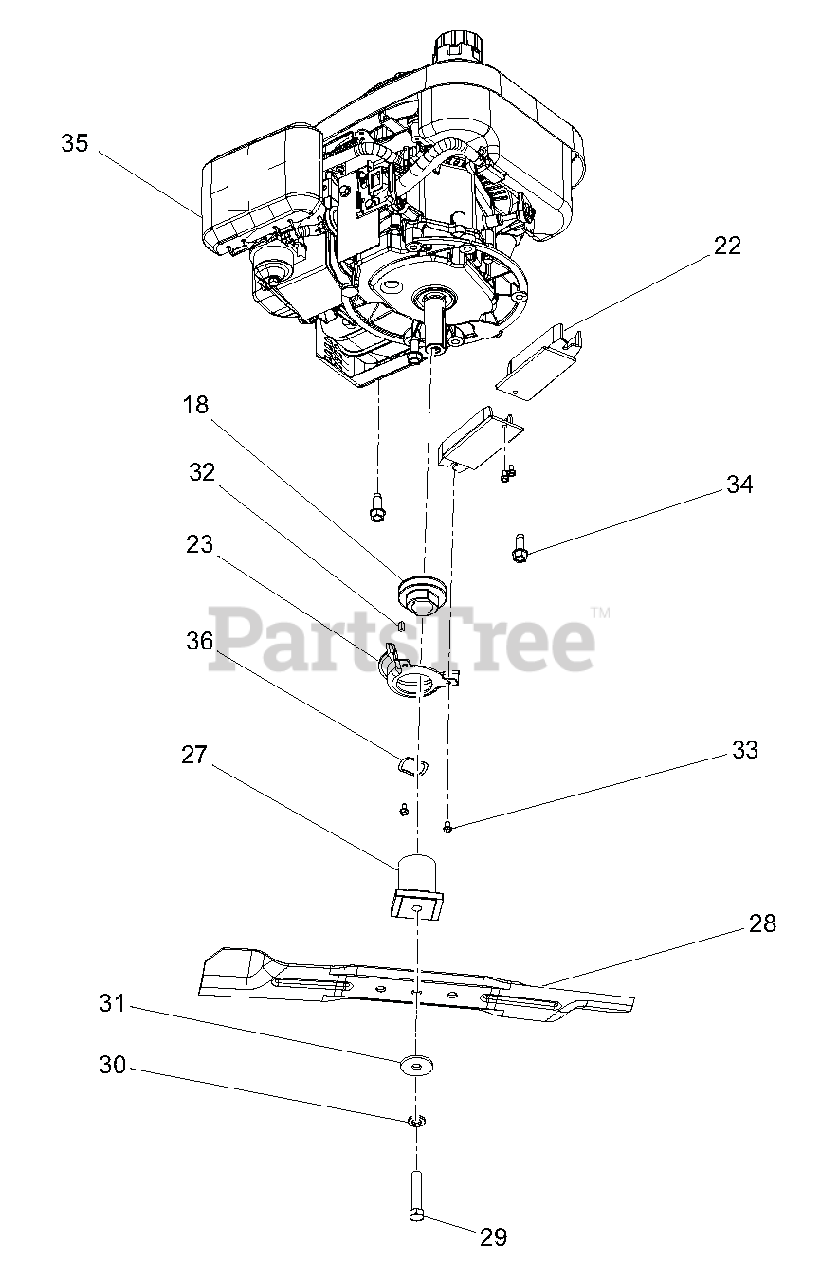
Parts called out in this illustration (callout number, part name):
18	MOTOR, WHEEL TG 0240
22	GUIDE, BELT INNER
23	GUIDE, BELT CRANK
27	ADAPTER, BLADE
28	BLADE, MOWER 21" HIGH LIFT
29	@BLT-HEX .4375-20X2.25 GR8 YWZ
30	@WSHR-LK .44X.109 REG YWZC
31	WSHR-FL-STL .4375X1.50X.125 YZ
32	KEY-SQ .188X.188X.625
33	SCR-TAP 10-24X.375 PRE-COAT 80
34	SCR-TAP (NO DRWG)
35	ENGINE,SERVICE,AC SERIES
36	WASHER - WAVE 1.09X1.37X.016
